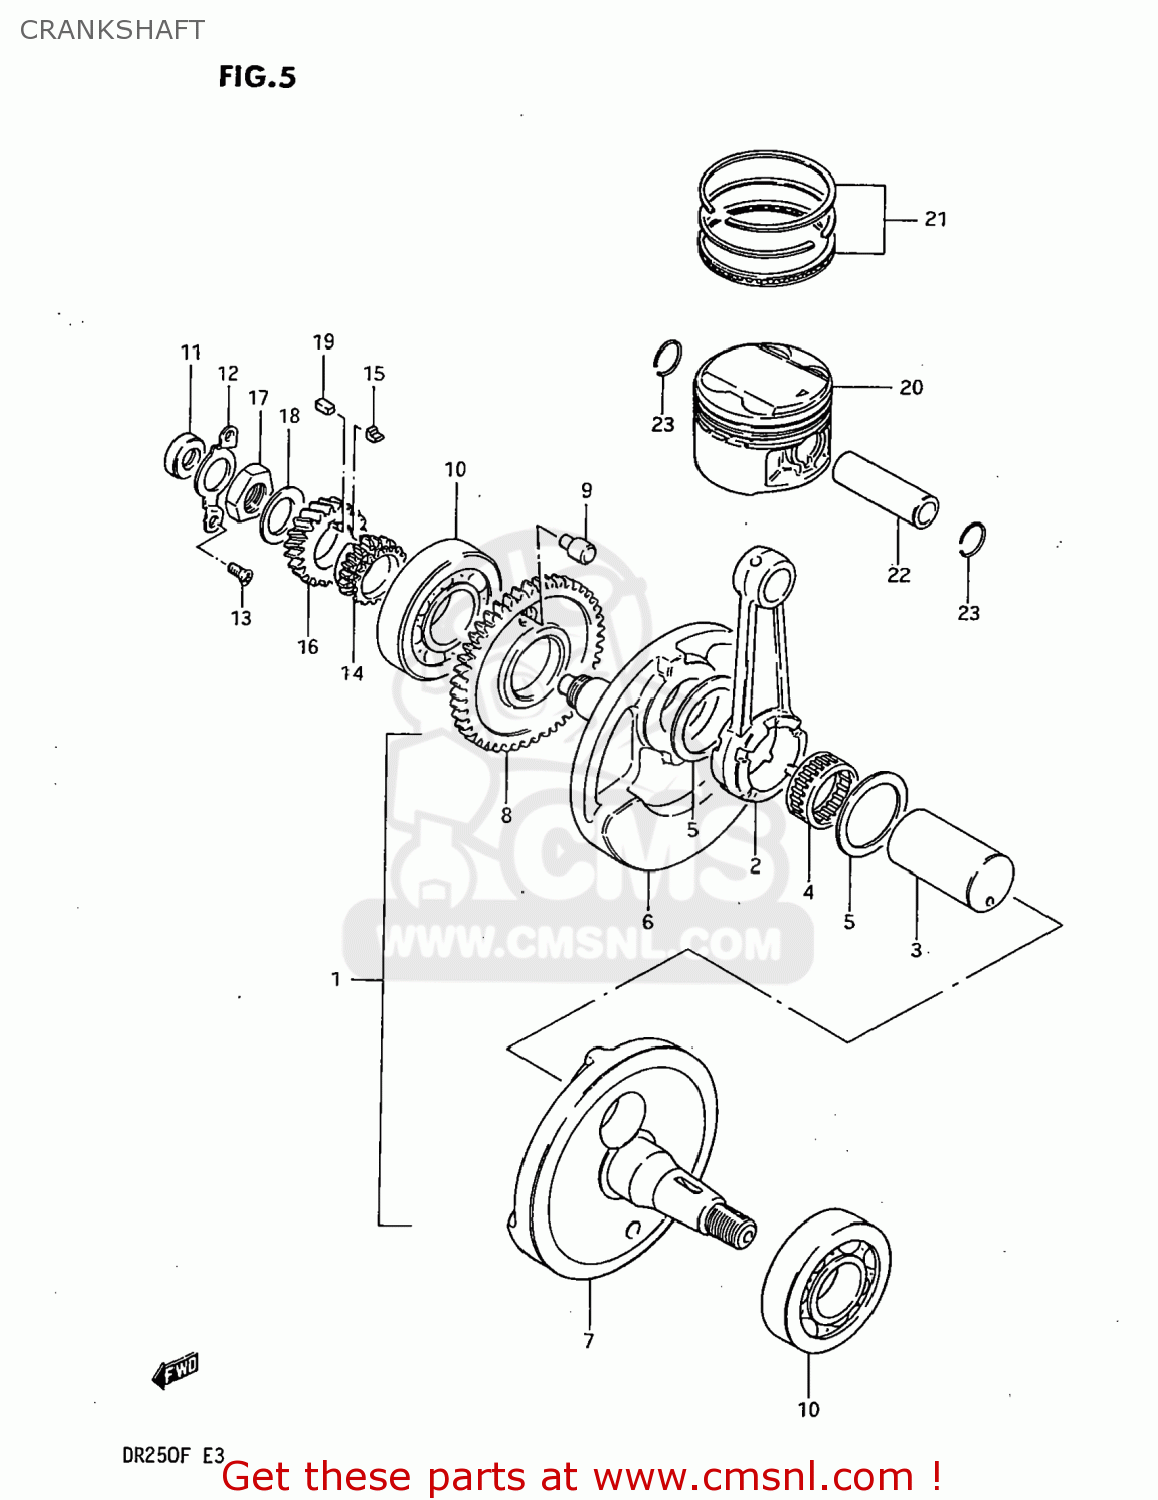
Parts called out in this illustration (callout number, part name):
1	CRANKSHAFT ASSEMBLY
2	ROD,CONNECTING
3	PIN,CRANK
4	BEARING
5	WASHER(31X48.5X1)
6	CRANKSHAFT,R
7	CRANKSHAFT,LEFT
8	GEAR,CRANK BALANCER DRIVE
9	PIN
10	BEARING
11	SEAL,OIL(14X26X6)
12	RETAINER,CRANKSHAFT BEARING,R
13	SCREW
14	SPROCKET,CAM CHAIN DRIVE(NT:21
15	KEY,SPROCKET
16	GEAR,PRIMARY DRIVE NO.21
17	NUT (20MM)
18	WASHER
19	KEY
20	PISTON
21	RING SET,PISTON
22	PIN,PISTON
23	CIRCLIP
